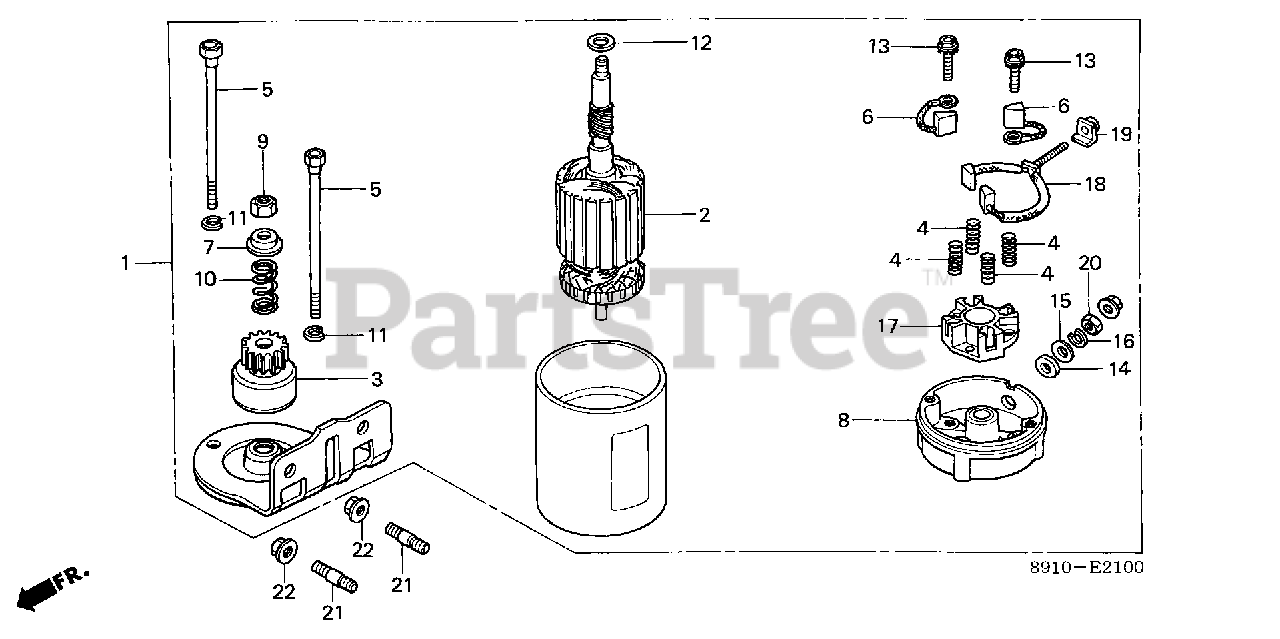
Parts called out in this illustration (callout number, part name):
1	STARTER MOTOR ASSY.
3	GEAR, PINION
4	SPRING, BRUSH
5	BOLT, THROUGH
8	COVER, RR.
10	SPRING, ANTI-DRIFT
11	WASHER A, LOCK
13	BOLT-WASHER
14	WASHER, INSULATION
16	WASHER B, LOCK
17	HOLDER, BRUSH
19	BUSHING
21	BOLT, STUD (8X30)
22	NUT, FLANGE (8MM)
